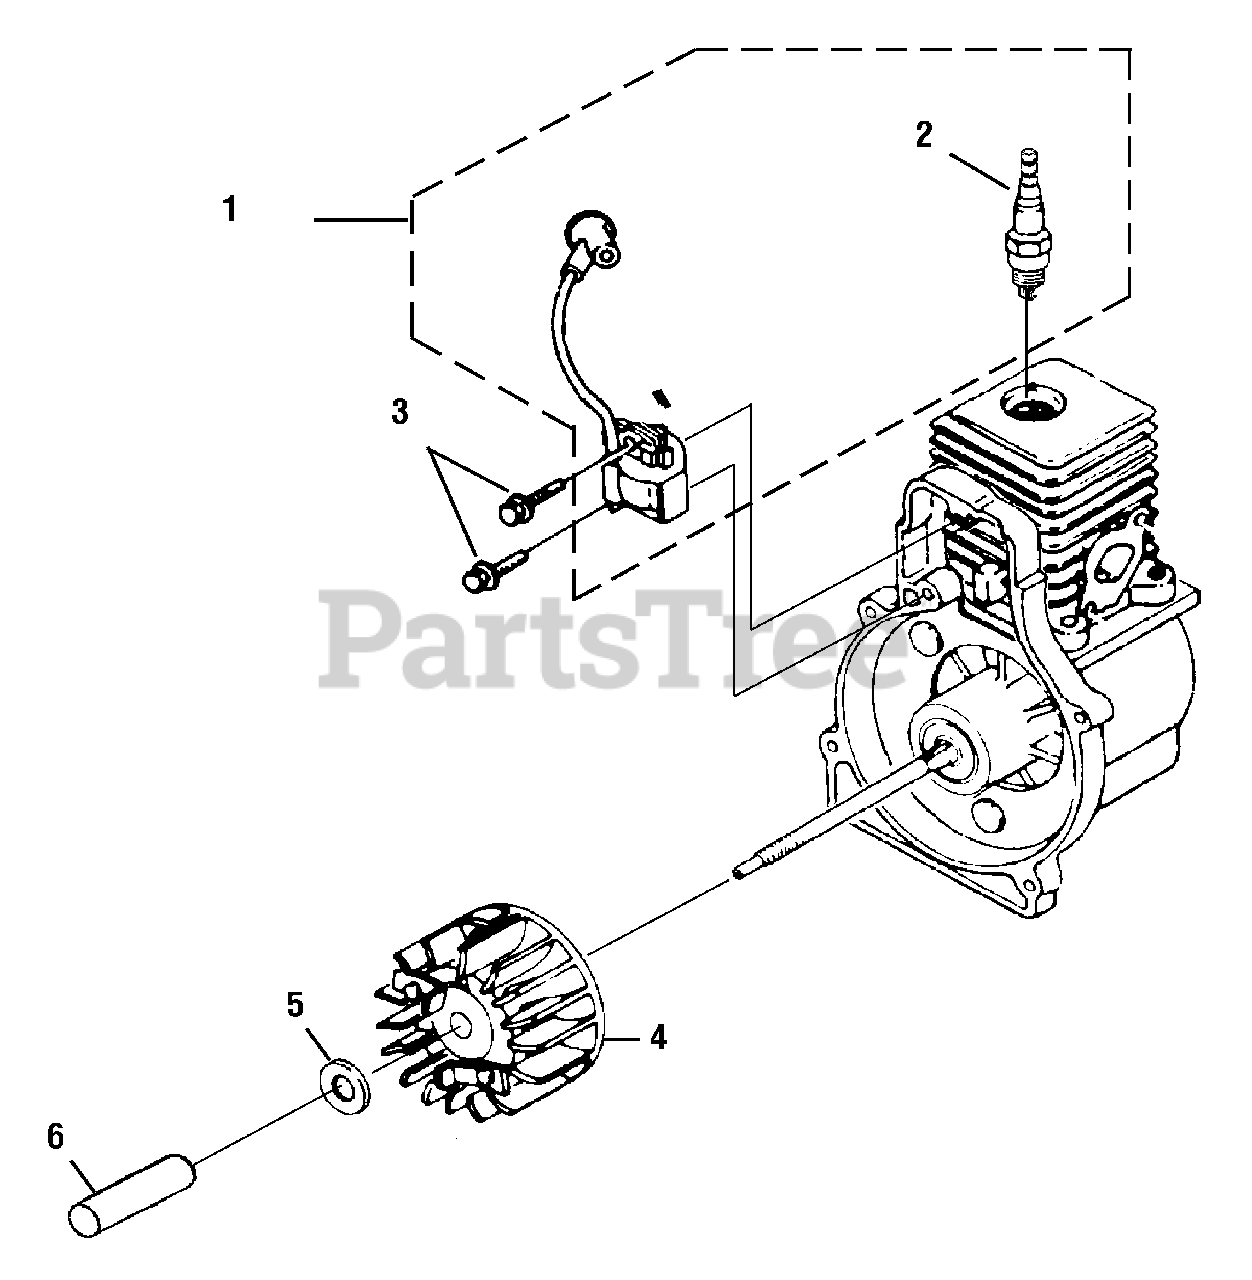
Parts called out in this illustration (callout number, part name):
1	IGNITION KIT WITH MODULE
2	SPARK PLUG
3	SCREW (8-32 x 1 in. TORX PAN HD.)
4	ROTOR AND STARTER PAWLS
5	FLAT WASHER
6	FAN SPACER
